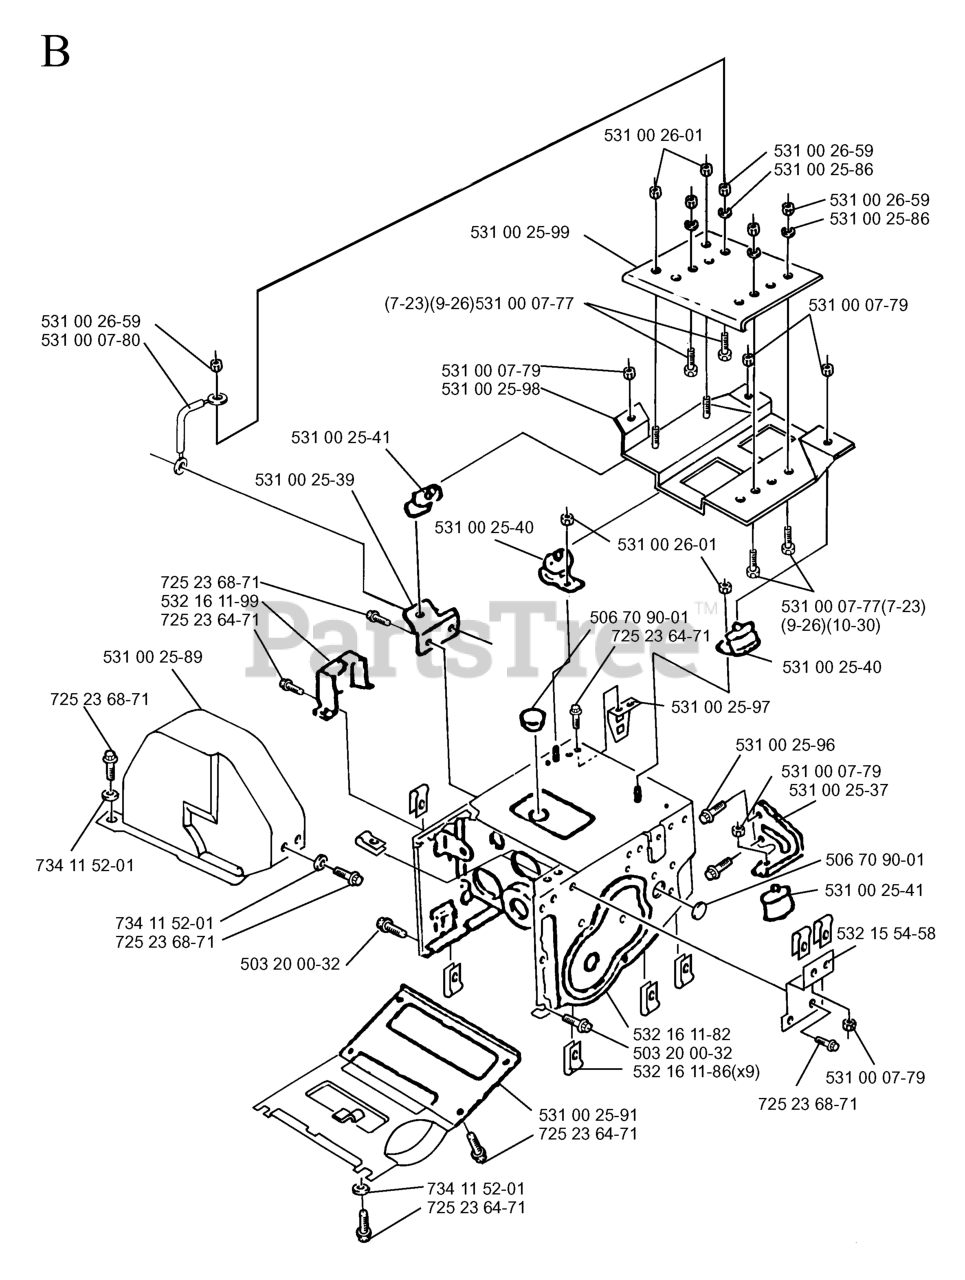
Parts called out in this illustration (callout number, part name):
2	KEY 1/4 X 2.5
7	HUB.ASM.WHEEL.REAR.23"TEX
15	WASHER
17	SPRING.BRAKE.HG3000/3500
26	SPRING.RETURN.CRUISE
33	E RING HYT
35	ROD.BRAKE.PARKING.GT.H
42	PEDAL COVER T
48	BOLT.3/8-16X1.50
50	IDLER.FLAT.910.OFFSET
51	NUT LOCK FLG 3/8-16 UNC
52	IDLER.V-GROOVE.910.OFFSET
56	V-BELT.GROUND.DRIVE.
64	SHAFT.ASM.PEDAL.BRK.CNTR
70	RP CONSOLE.ASM.PCH.W/TB
73	BOLT HEX FLGHD 5/16-18X3 GR. 5
74	SCREW.HI-LO.CONSOLE
80	STRAP.TORQUE.YT.G700
92	BOLT
99	SPRING.BYPASS.YT.G700
114	NUT.71038.31-18.HEX.NYLOCK
116	NUT LOCK HEX FLANGE 5/16-18
121	BRACKET STRAP TORQUE
125	SCREW
145	WASHER.AXLE.FLANGE.HG-3000
153	RETAINER M
159	COTTER PIN
160	RETAINER CLIP
161	SPRING, RETURN LT
163	ROD PEDAL CONTROL
166	NUT.PUSH.625
167	LATCH.BRAKE.SPRING
184	HANDLE.PARKG.BRK.HUSQ X667
186	SPACER.RETAINER
187	WASHER 12/32X2X10GA
188	RP.LINK.CLUTCH.GROUND.DRIVE
189	BELLCRANK.GROUND.DRIVE.TRAPPED
190	KEEPER BELLCRANK ROUND DRIVE
196	SCREW 3/8-16X1
197	BRKT.ANIT-ROTATION.CLUTCH
203	WASHER
206	BRKT.MOUNT.LATCH.CRUIS
207	LATCH.CONTROL.CRUISE
208	GEAR.SECTOR.CONTROL.CR
209	ROD.CONTROL.CRUISE.GT.
210	ROCKER.ASM.PEDAL.CONTR
211	BEARING.NYLON
213	KNOB.CONTROL.CRUSIE.HU
214	PEDAL.FORWARD.HUSQVARNA.DEALER
215	PEDAL.REVERSE.TEX.GT.4
220	REFLECTOR.RH.TEX GT
221	RETAINER.SPRING.CLIP.H
222	WASHER 21/32 X 1-1/4 X 10 GA.
284	NUT.U-CHNL.1/4-20.550DP.350PNL
285	SCREW.PHD.1/4-20.BOX DRVE
286	BOLT.5/16-18X2.5
306	PIN COTTER
